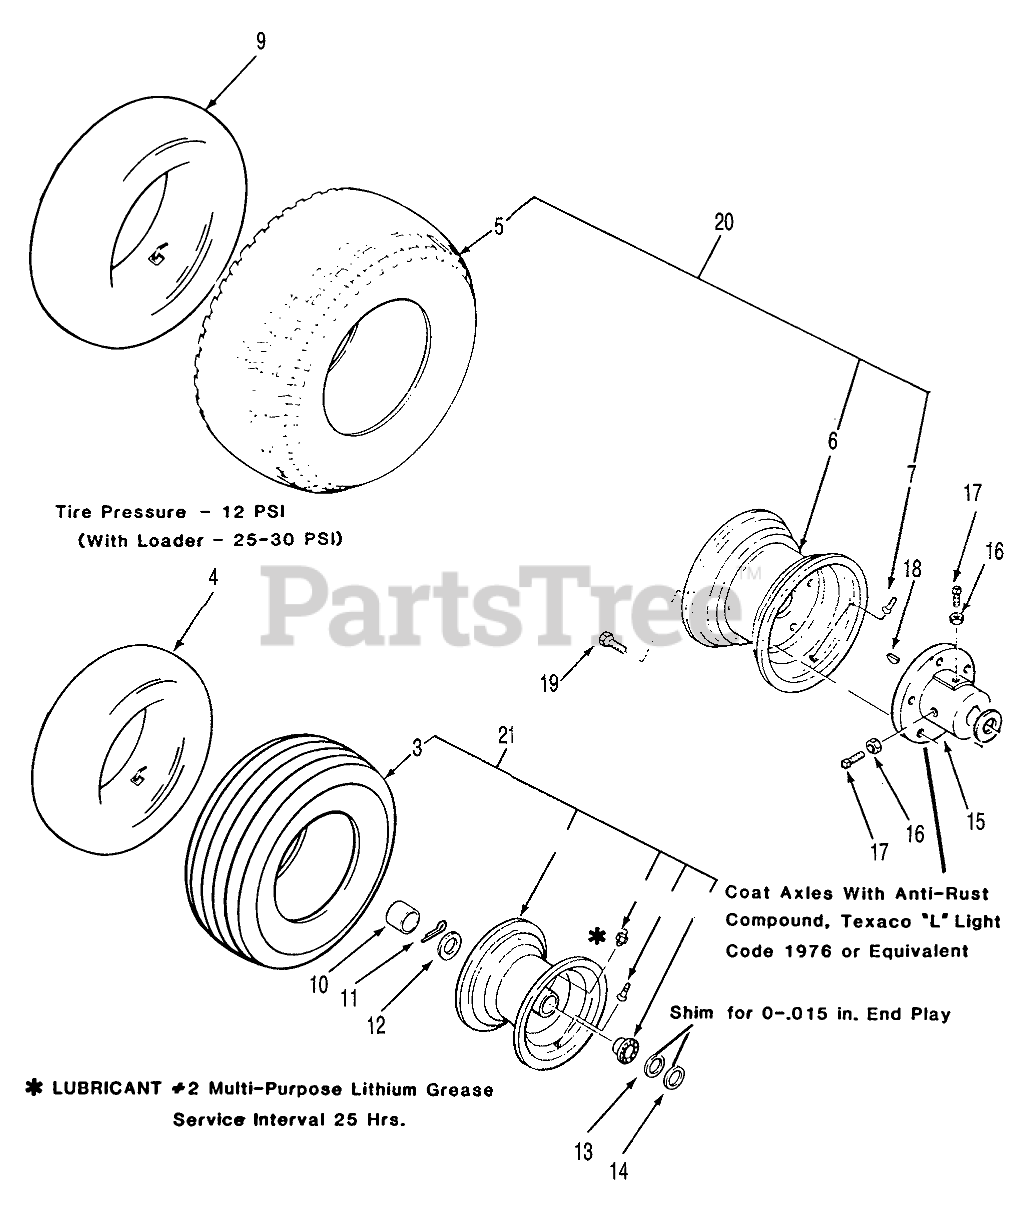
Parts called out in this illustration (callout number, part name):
1	ZERK-GREASE
2	Front Wheel (includes item 1, 10, 11)-312-8
3	TIRE-15 X 6.00-6
5	TIRE
6	WHEEL
7	VALVE
8	BEARING-WHEEL
9	TUBE-INNER
10	HUB CAP-FLAT BLACK
11	COTTER PIN-4
12	WASHER-WHEEL
13	WASHER
14	WASHER-SHIM
15	Hub Rear
16	Nut
17	Screw-Set
18	KEY-WOODRUFF
19	Lug Nut
20	ASM-Wheel& Tire
21	ASM-Wheel & Tire
